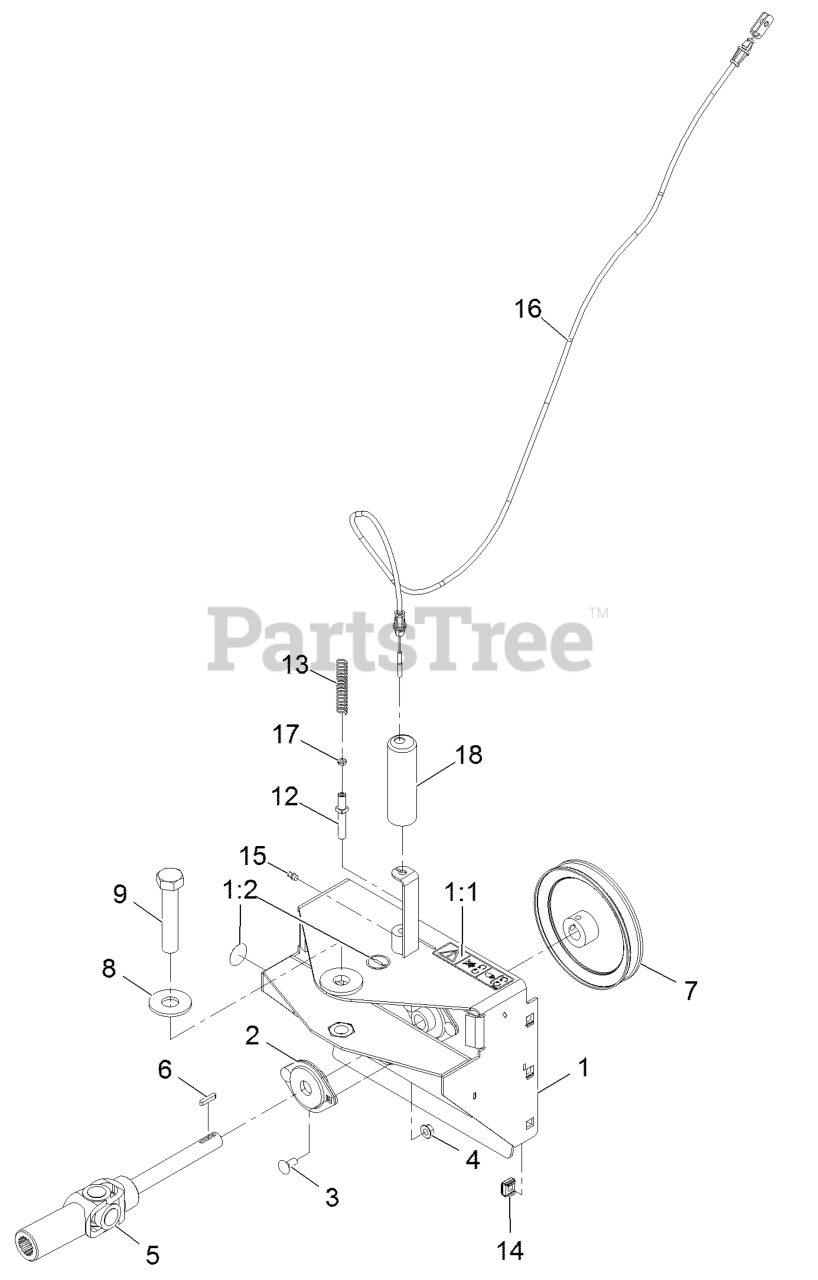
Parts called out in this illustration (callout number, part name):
1	BROOM MOUNTING FRAME ASM
1:1	DECAL-COVER, MISSING
1:2	DECAL-GREASE
2	BEARING-SHAFT
3	BOLT-CARR
5	SHAFT-DRIVE
6	KEY-ROUND END
7	PULLEY-IMPELLER
8	WASHER-FLAT
9	SCREW-HH
12	PIN-SWING
13	SPRING-COMPRESSION
14	NUT-RETAINER
15	FITTING-GREASE
16	CABLE-ANGLE, BROOM
17	NUT-HEX
